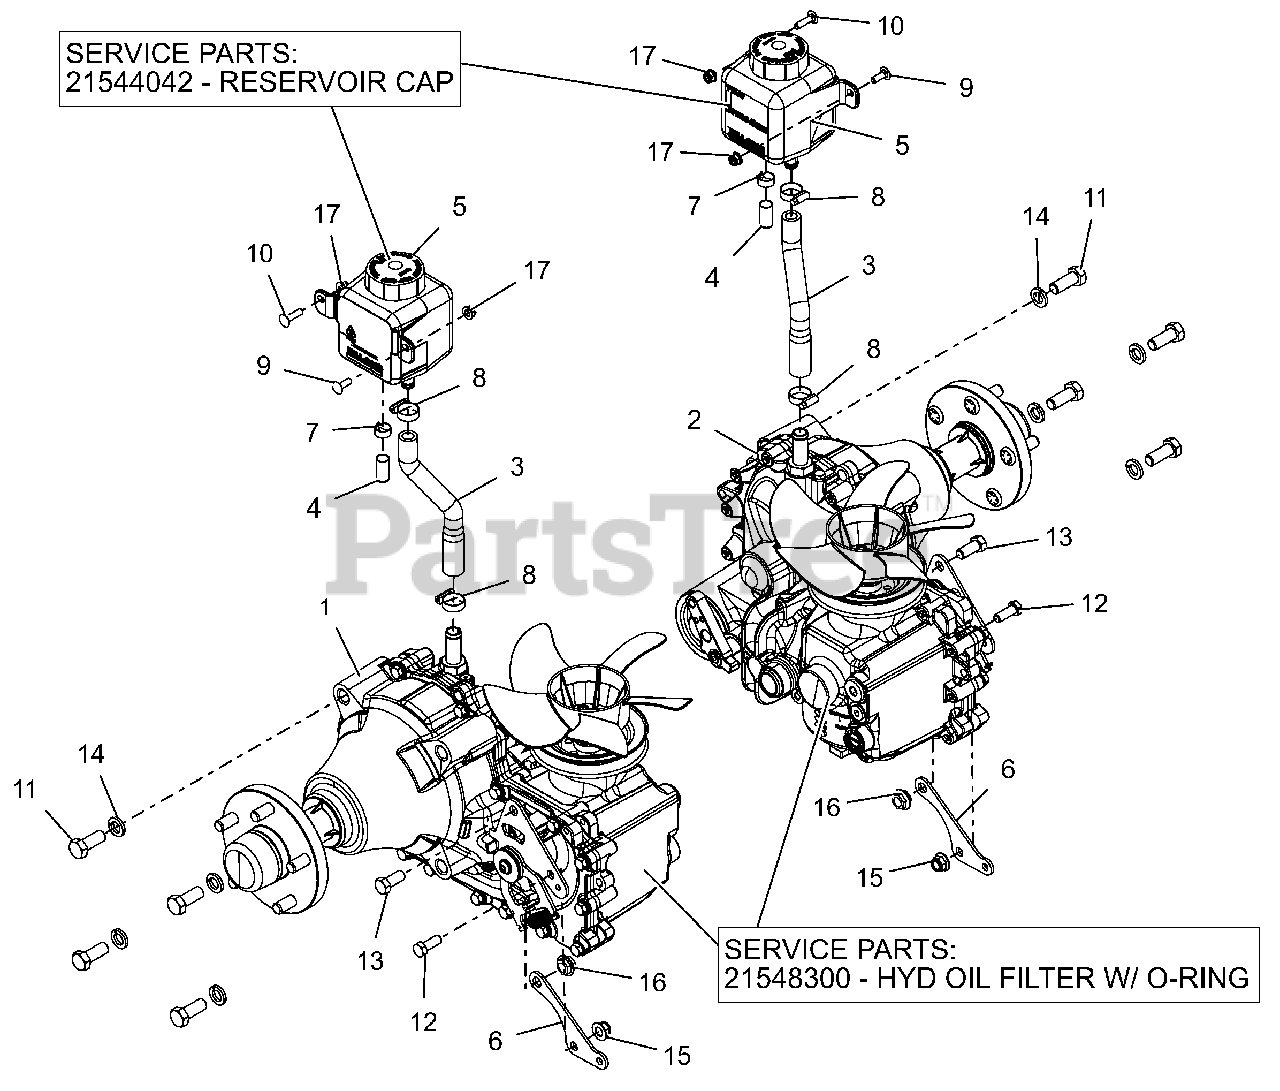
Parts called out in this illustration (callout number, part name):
1	TRANS, RH HG ZT-5400
2	TRANS, LH HG ZT-5400
2	FILTER,HYD OIL W/ORING ZT-54OO
3	HOSE,PT200/400 TRANS OVERFLOW
4	CAP, .50 BARBED FITTING
5	TANK, HYDRO OVERFLOW 700 ML
5	CAP, HYDRO RESERVOIR REPLAC.
6	DRV CNTRL LINKAGE MTG BRKT-BLK
7	CLAMP, .62 SPRING
8	CLAMP,.88 DIA. HOSE
9	@BLT-RDHDSQNK .25-20X.75 G5YZ
10	@BLT-RDHDSQNK .25-20X1.00 G5YZ
11	@BLT-HEX .50-13X1.25 GR5 YWZC
12	@BLT-HEX .38-16X1.00 GR5 YWZC
13	@BLT-HEX .44-14X1.00 GR5 YWZC
14	@WSHR-LK .50X.125 REG YWZC
15	@NUT-LK-NYL-FLG .38-16 YWZC
16	@NUT-LK-NYL-FLG .44-14 YWZC
17	@NUT-LK-NYL-FLG .25-20 YWZC
